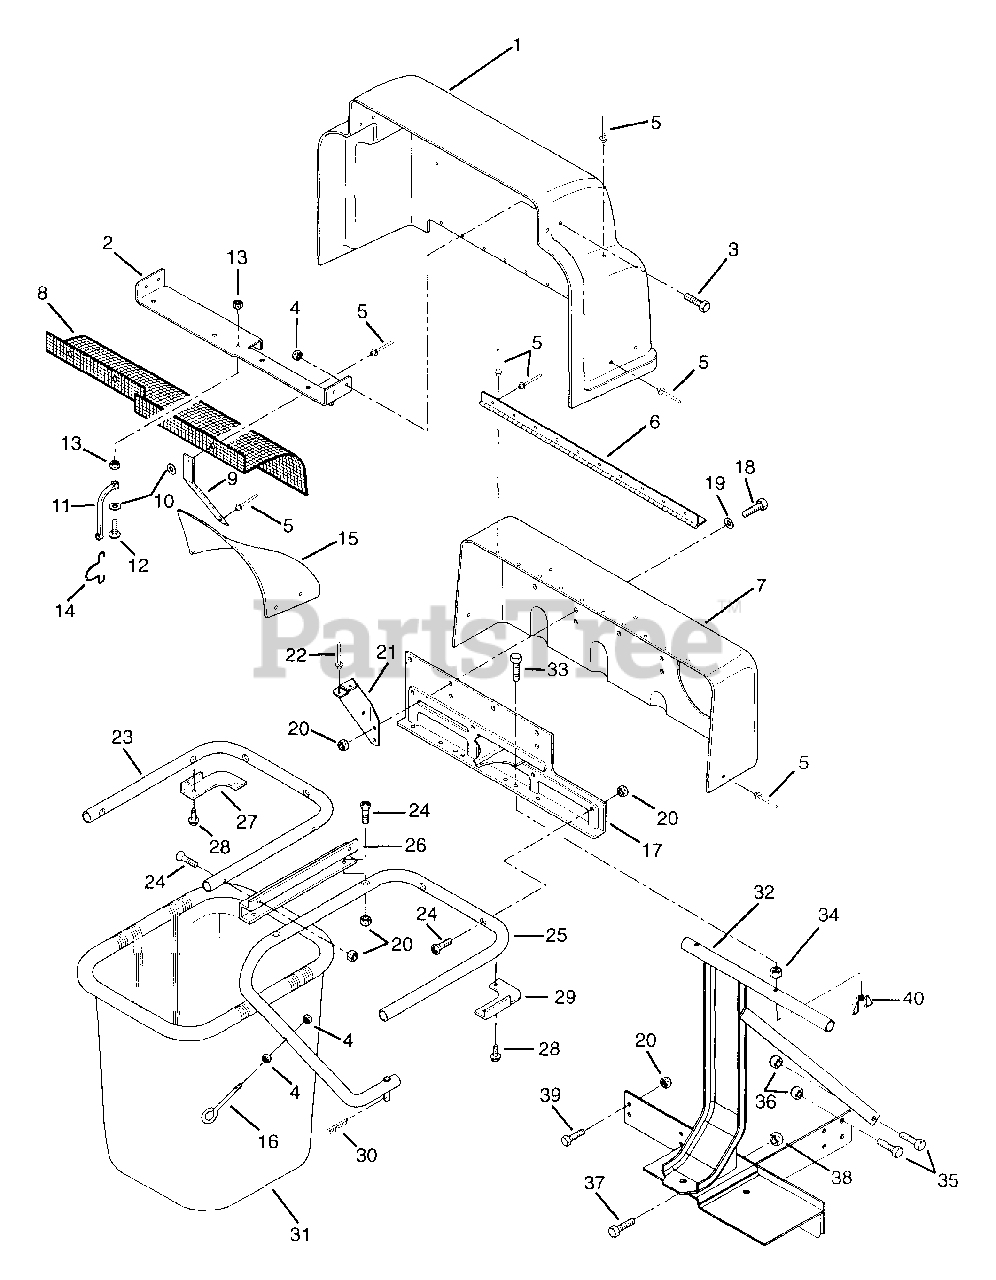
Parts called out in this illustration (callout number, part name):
1	HINGED COVER W/DECALS
2	COVER BRACKET
3	BLT-HEX .25-20X.50 PL GR2
4	NUT-LK-CTR .250-20 PL
5	RVT-POP .187X.402 DOME ST
7	STATIONARY COVER
10	WSHR-FL-STL .194X.492X.047 PL
11	BATTERY STRAP
12	SCR-MCH 10-24X.88 SLRH PL
13	NUT-LK TOP 10-24 PL
16	EYEBOLT
17	MOUNTING BRACKET
18	BLT-HEX .31-18X.88 PL GR2
19	WSHR-FL-STL .344X1.125X.063PL
20	NUT-LK .312-18 GR A PL
22	RVT-POP.187X.527 DOME ST
23	CENTER TUBE
24	SCR-MCH .31-18X1.50 CROVCNTRS
25	RIGHT TUBE
26	TUBE BRACKET
27	LH CORNER BRACKET
28	SCR-TAP .312-18X.50 HWH PL TR
29	RH CORNER BRACKET
30	PIN-HAIR INT .08X.38X1.42 YWZC
31	GRASS BAGGER BASKET
32	BAGGER FRAME
33	BLT-HEX .31-18X1.50 GR2 YWZC
34	NUT-HEX .312-18
35	BLT-HEX .38-16X1.25 GR5
36	NUT-LK-NYL .375-16 PL
37	@BLT-HEX .50-13X1.00 GR5 YWZC
38	NUT-LK-CTR .50-13
39	@BLT-HEX .31-18X1.00 GR5 YWZC
40	NUT-WING W/INSERT .312 - 18
